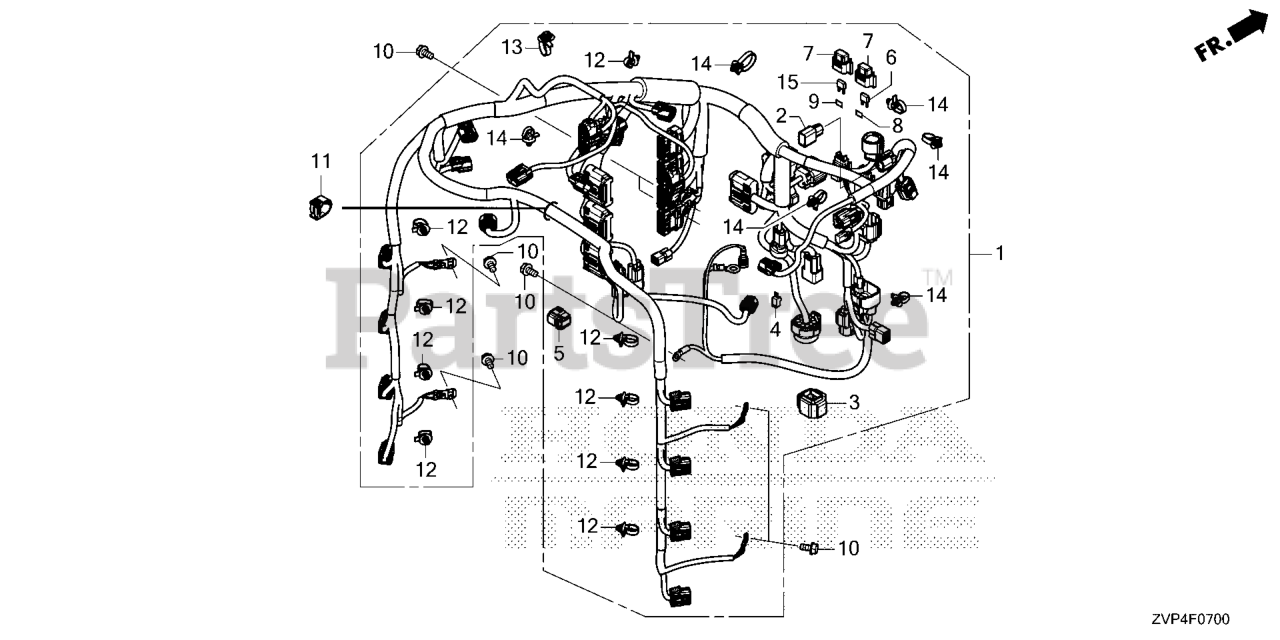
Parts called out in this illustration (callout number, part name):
1	HARN, MAIN WIRE
2	TERMINATOR ASSY.
3	SUSPENSION, CONNECTOR
4	CONNECTOR, DIODE (2P) (3A)
5	CAP, DUMMY (WPC 4P 090 M) (RED)
6	FUSE, BLADE (3A)
7	COVER ASSY., FUSE
8	LABEL, FUSE (3A)
9	LABEL, FUSE (7.5A)
10	BOLT, FLANGE (6X12)
11	CLIP, WIRE HARNESS
12	CLIP, HARNESS BAND (151.5MM) (NATURAL)
13	CLIP, HARNESS BAND (157.7MM) (BLACK)
14	CLIP, HARNESS BAND (145MM) (BLACK)
15	FUSE, MINI (7.5A)
